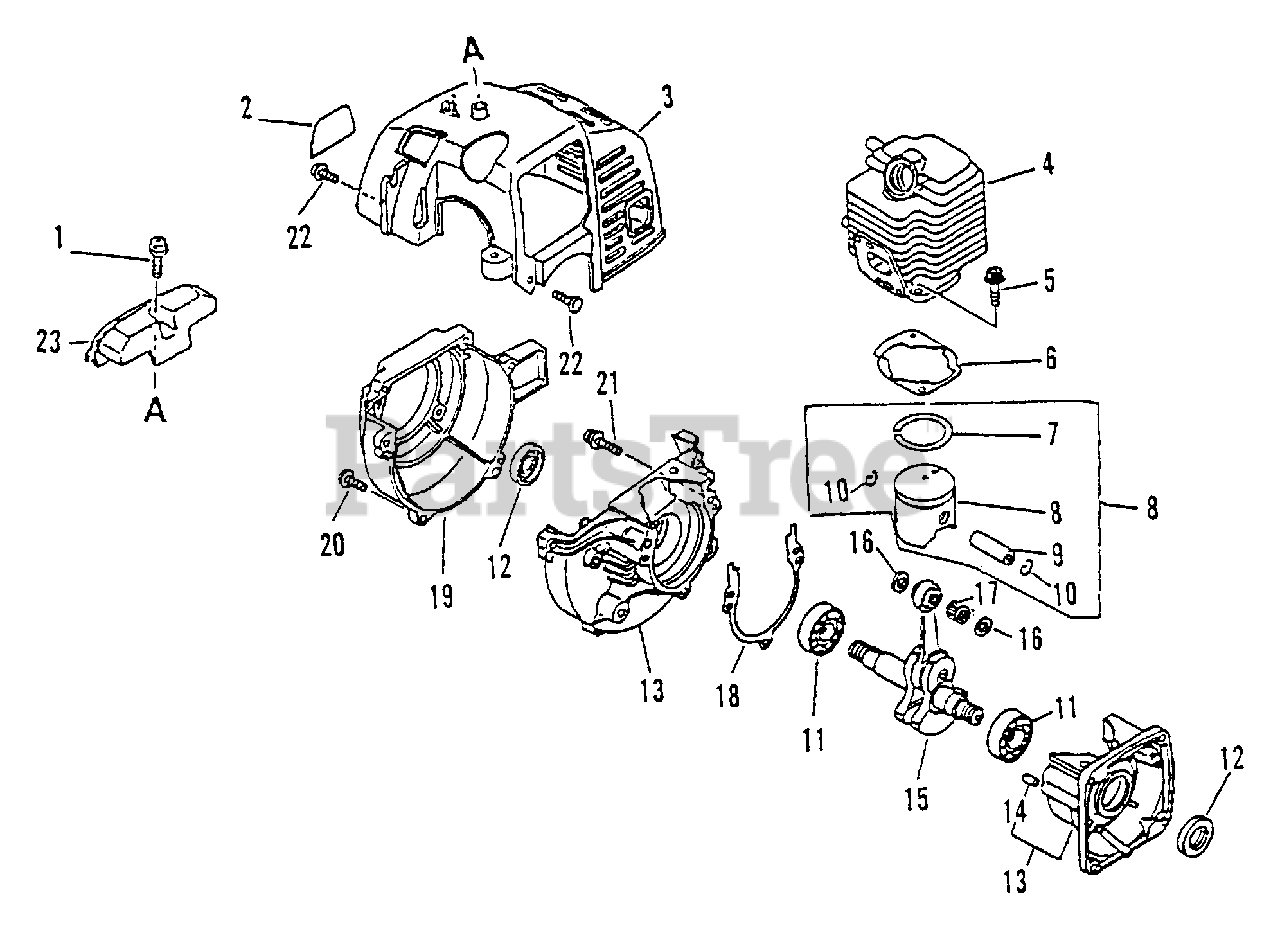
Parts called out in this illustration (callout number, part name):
1	SCREW 5×16
2	LABEL, PE-2400
3	COVER, ENGINE - GRAY
4	CYLINDER
5	BOLT 5×22
6	GASKET, CYLINDER
7	RING, PISTON
8	PISTON KIT
9	PIN, PISTON 8
10	RING, SNAP
11	BEARING, BALL - 6201 C3
12	SEAL, OIL 12
13	CRANKCASE KIT
14	PIN, LOCATING 4
15	CRANKSHAFT ASSY
16	WASHER, THRUST
17	BEARING, NEEDLE
18	GASKET, CRANKCASE
19	COVER, FAN - GRAY
20	SCREW 4×16
21	BOLT 5×28
22	SCREW 4×12
23	GUARD, TOP - BLACK
